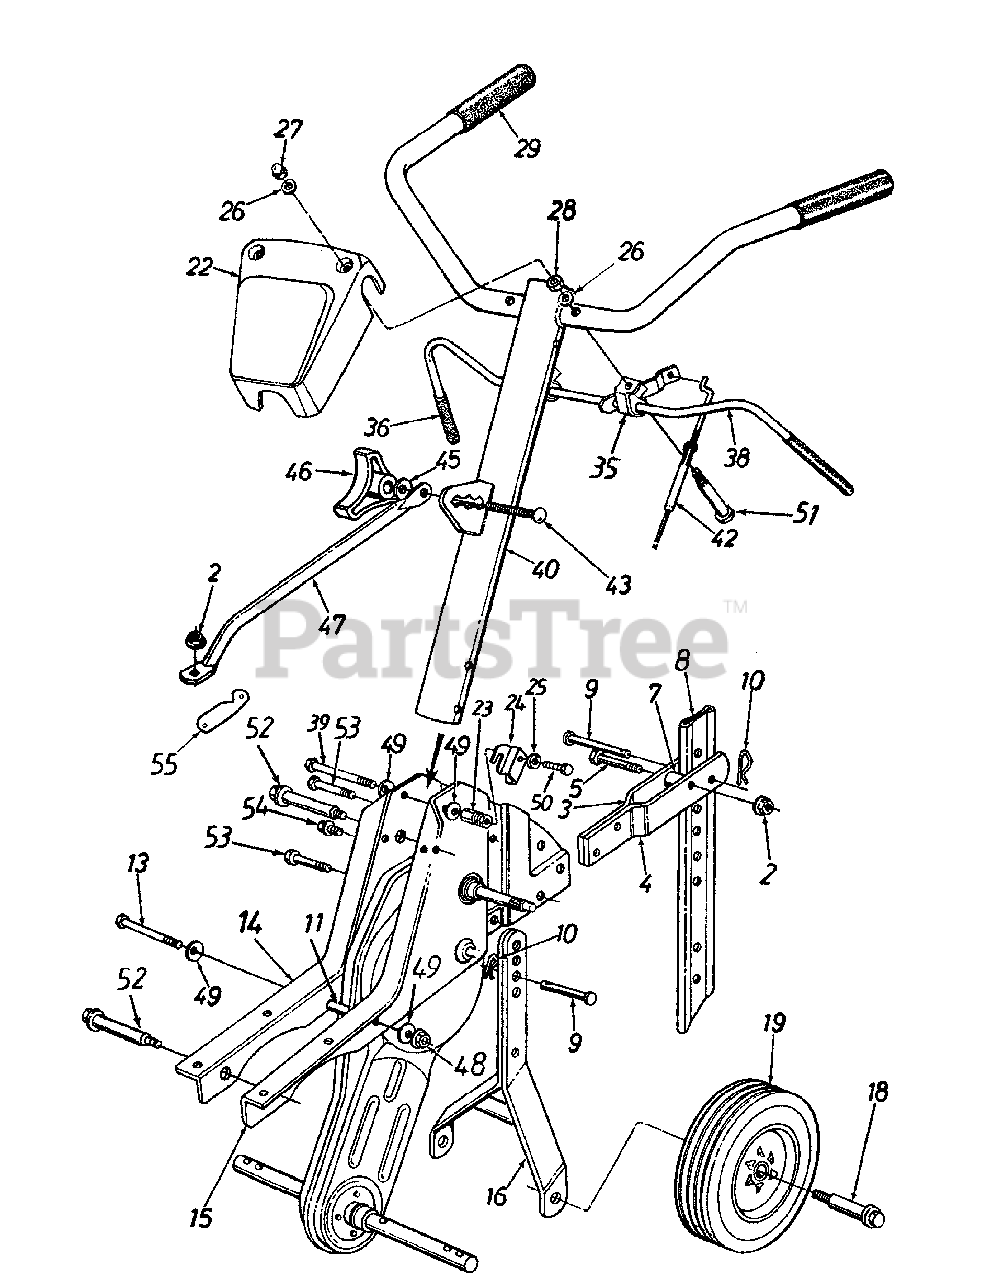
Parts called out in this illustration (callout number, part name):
2	Hex Flange L-Nut 5/16-18 Thd.(Gr. 5)
4	Tail Piece Brkt. (L.H.)
5	Hex Bolt 5/16-18 x 1.5" Lg.
7	Spacer .32" I.D. x .75" O.D.
9	Clevis Pin .375" I.D. x 1.62" Lg.
10	Internal Cotter Pin
11	Spacer .326" I.D. x .47" O.D.
13	Hex Bolt 5/16-18 x 2.75" Lg.
14	Frame - R.H.
15	Frame - L.H.
18	Shld. Bolt .498" Dia. x 1.45" Lg.
19	Wheel Ass'y.
22	Handle Cover
23	Spec. Hex Nut
25	L-Wash. 5/16" I.D.*
26	Fl-Wash. .266" I.D. x .625" O.D.
27	Hex L-Stop Nut 1/4-28 Thd.
28	Hex Nut 1/4-20 Thd.
29	Grip - Handle
35	Clutch Handle Holder
36	Grip - Clutch
39	Hex Bolt 5/16-18 x 3" Lg.*
40	Longhorn Handle Ass'y.
42	Clutch Control Cable
43	Carr. Bolt 5/16-18 x 1" Lg.(Spec.)
45	Wash. Bell. .340' I.D.x .872 O.D.
46	Hand Knob
47	Engine Tubing Brace
48	Hex L-Nut 5/16-18 Thd.
49	Bell-Wash. .345" I.D. x .88" O.D.
50	Hex Bolt 5/16-18 x .75" Lg.(Gr. 5)
51	Hex Bolt 1/4-20 x 2.25" Lg.
52	Shld. Bolt
53	Hex Hd. Tap Scr.5/16-18 x .62"
54	Hex Wash. Hd. TT-Tap Scr.5/16-18 x 1" Lg.
55	Engine Bracket
